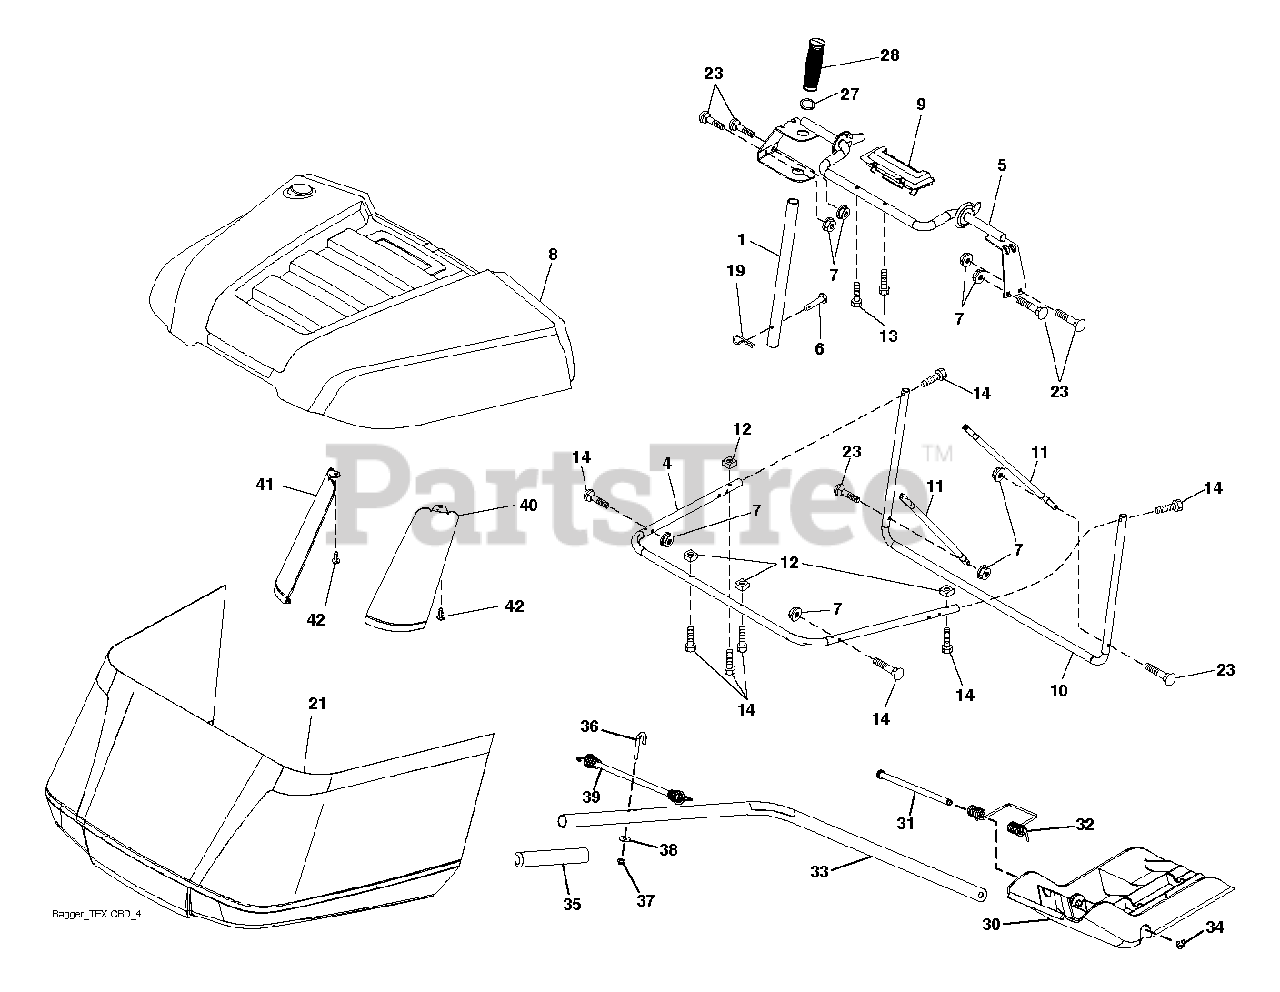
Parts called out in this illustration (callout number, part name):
1	TUBE.HANDLE.BAGGER.CRD/SRD.BLA
4	SUBASM.TOP.TUBE.TEX.CRD
5	FRAME.ASM.TOP.BAGGER.SRD
6	RIVET,DRILLED
7	NUT T
8	BAGGER.TOP.SUB.ASSEM.SRD
9	INSERT.HANDLE.BAGGER.(2 2)
10	FRAME FRAME.FRONT.TEX.CRD
11	BRACE BRACE SIDE TUBE
12	NUT.SQUARE.1/4
13	SCREW.1/4X1.150.HXWSH
14	BOLT.SHOULDER.HX.WSH.1/4X1.150
19	PIN.COTTER.5/16.BOW TI
27	RB GROMMET.RUBBER.SRD
28	GRIP.HANDLE.BLACK
30	PLUG PLUG
31	PIN PIN.HINGE
32	SPRING SPRING DOUBLE TORSION
33	SHAFT SHAFT TEX CRD MULCH PLU
34	E-RING.5/16"
35	GRIP GRIP MULCH PLUG HAND
36	BOLT BOLT J
39	BUBGEE BUBGEE TEX CRD
42	CLIP CHRISTMAS TREE CLIP
